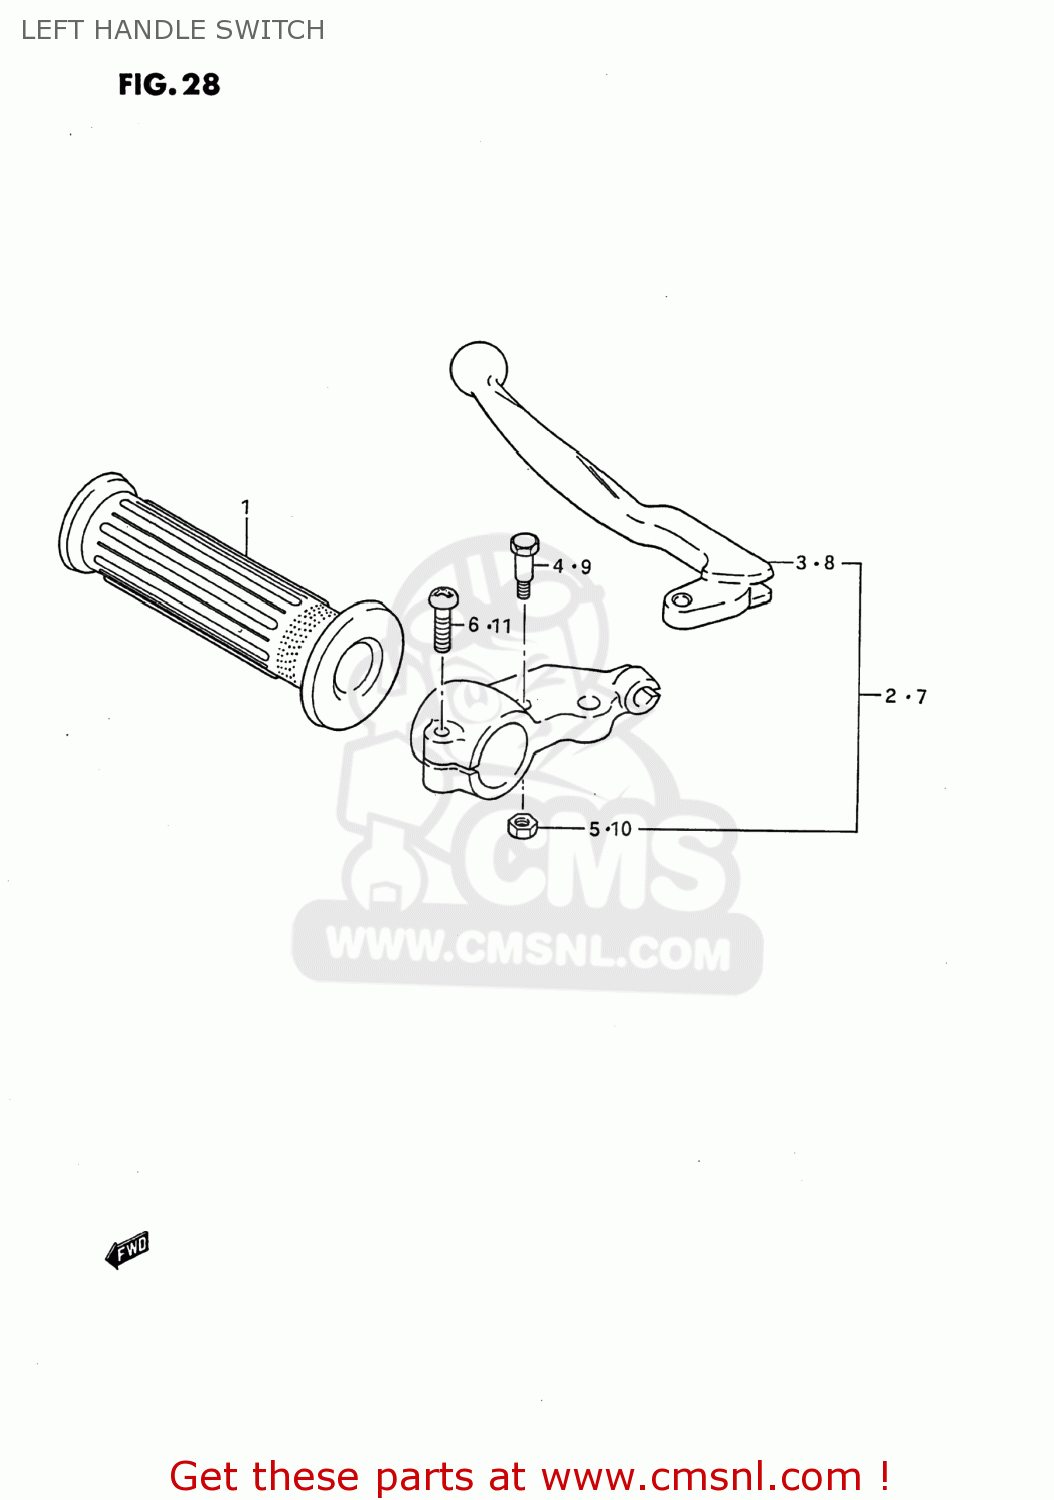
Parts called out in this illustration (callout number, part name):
1	GRIP,L
2	LEVER ASSY,CLUTCH
3	LEVER,CLUTCH
4	BOLT,LEVER PIVOT
5	NUT 5MM
6	SCREW
7	LEVER ASSY,CLUTCH
8	LEVER,CLUTCH
9	SCREW
10	NUT 8MM
11	SCREW
